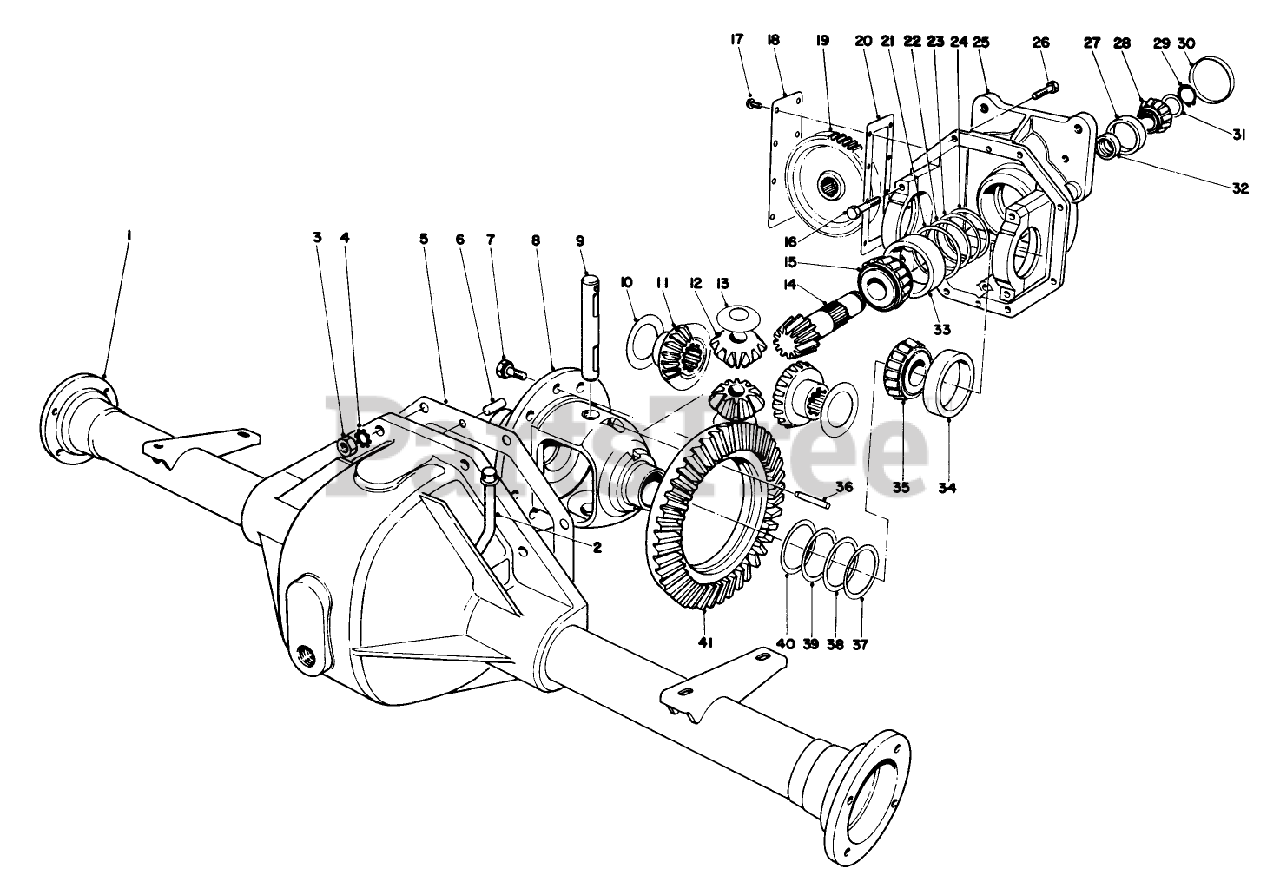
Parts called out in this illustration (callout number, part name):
1	Lower Housing & Tube Ass-y
2	Vent Assembly
3	NUT-HEX
4	WASHER-LOCK
5	HSG GASKET
6	PIN-DOWEL
7	SCREW-GEAR, DRIVE
8	CASE-DIFFERENTIAL
9	SHAFT-MATE, PINION
10	WASHER-THRUST
11	GEAR-DIFFERENTIAL
12	PINION-DIFFERENTIAL
13	WASHER-THRUST, PINION
15	ROLLER BRG CONE
16	SCREW-HH
17	SCREW
18	COVER-GEAR
19	Gear-Spur
20	GEAR COVER GASKET
21	REAR PINION BRG SHIM
22	BRG SHIM .005
23	BRG SHIM .010
24	BRG SHIM .030
25	Upper Housing Assembly (Incl. Ref. #16)
26	Screw
27	BEARING-CUP
28	BRG CONE
29	Retaining Ring
30	PLUG-CUP
31	FRT PINION BRG SHIM
32	SPACER-BEARING
33	ROLLER BRG CUP
34	CUP-BEARING, ROLLER
35	BEARING-ROLLER, CONE
36	Pin-Roll
37	SHIM-BEARING, DIFFERENTIAL (.003)
38	SHIM-BEARING, DIFFERENTIAL (.005)
39	SHIM-BEARING, DIFFERENTIAL (.010)
40	SHIM-BEARING, DIFFERENTIAL (.030)
41	Ring Gear
